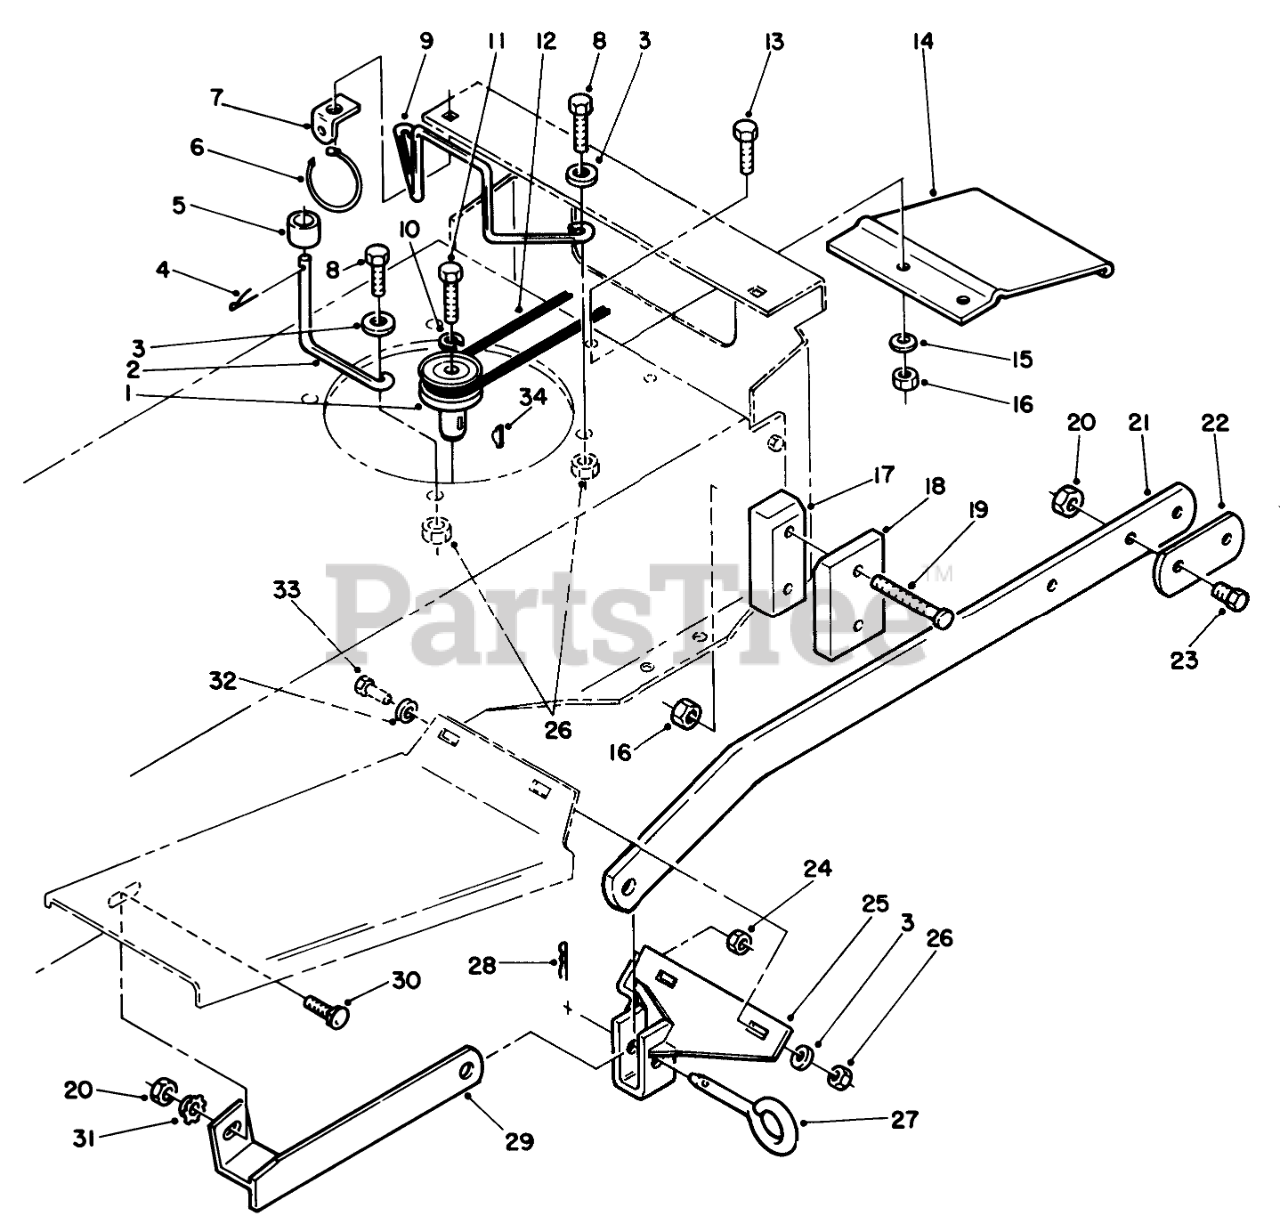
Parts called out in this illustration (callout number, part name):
1	PULLEY-DRIVER
2	Guide-Belt
3	WASHER-PLAIN
4	PIN-COTTER
5	SPACER
6	TIE-PLASTIC
7	CLIP - SPRING
8	SCREW-HH
9	BELT-GUIDE
10	WASHER-LOCK
11	Screw
12	V-BELT
13	SCREW-HH
14	SHOE-BELT R
15	WASHER-FLAT
16	NUT-LOCK, NI
17	SPACER-RUB BLOCK R
18	Block Rubber
19	Screw-Pan Hd.
20	NUT-LOCK, NI
21	Bar-Pivot
22	SPACER R
23	SCREW-HH
24	Nut
25	ASS'Y-BRACKET LH R
26	NUT-LOCK, NI
27	PIN-TOOL
28	Hairpin Cotter
29	WELDMENT-BRACE L. R
30	BOLT-CARR
31	WASHER
32	WASHER-SPECIAL
33	SCREW-HH
34	HARD HI PRO KEY
